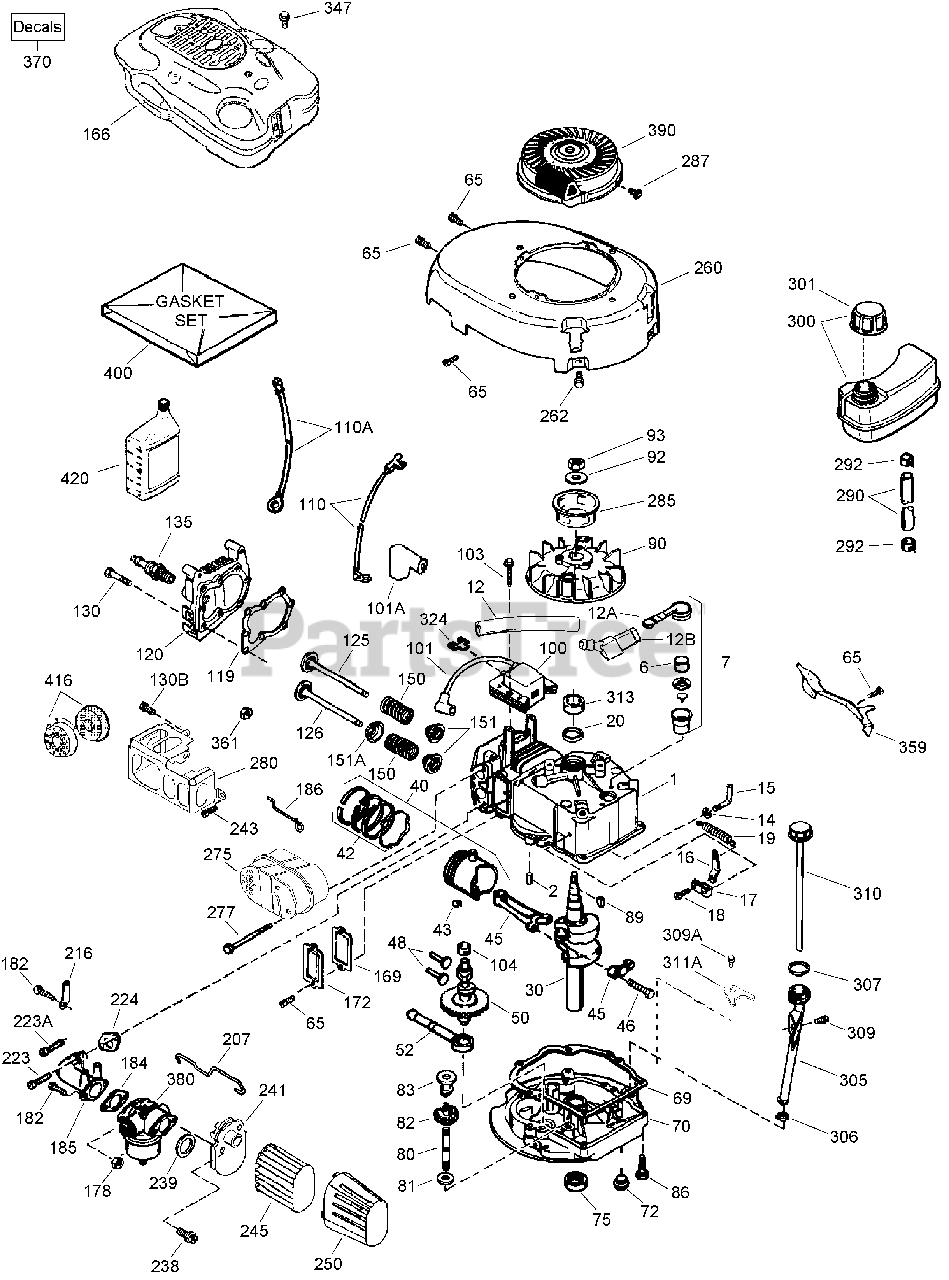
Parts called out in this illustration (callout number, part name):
1	Cylinder ASM (Includes 2 and 20)
2	Pin-Dowel
6	Element-Breather
7	Breather ASM (Includes 6 and 12A)
12	Tube-Breather
12A	Breather Cover and Tube ASM (Includes 12B)
12B	Elbow-Tube, Breather
14	Washer-Flat
15	Governor Rod ASM (Includes 14)
16	Lever-Governor
17	Clamp-Lever, Governor
18	Screw (T-15, 8-32 x 19/64)
19	Spring-Extension
20	Seal-Oil
30	Crankshaft
40	Piston, Pin and Ring Set (STD) (Includes 42)
40	Piston, Pin and Ring Set (.010 OS) (Includes 42)
42	Ring Set (STD)
42	Ring Set (.010 O S)
43	Ring-Retaining, Piston Pin
45	Connecting Rod ASM (Includes 46)
46	Bolt-Rod, Connecting
48	Lifter-Valve
50	Camshaft ASM (Exhaust MCR) (Incudes 104)
52	Oil Pump ASM
65	Screw (10-24 x 9/16)
69	Gasket-Flange, Mounting
70	Mounting Flange ASM (Includes 72 thru 83, 306, 309A and 311A)
72	Plug-Drain, Oil (Flush Mount)
75	Seal-Oil
80	Shaft-Governor
81	Washer
82	Governor Gear ASM (Includes 81)
83	Spool-Governor
86	Screw (1/4-20 x 1-1/4)
89	Key-Flywheel
90	Flywheel
92	Washer-Belleville
93	Nut-Flywheel
100	Ignition-Solid State
101	Cover-Spark Plug
101A	Shield-Spark Plug L-Head
103	Screw (T-15, 10-24 x 15/16)
104	Bushing-Cam
110	Wire-Ground
110A	Wire-Ground (10.50 with male and female flag terminals)
119	Gasket-Head, Cylinder
120	Head-Cylinder
125	Valve-Exhaust (STD) (Includes 151)
125	Valve-Exhaust (1/32 OS) (Includes 151)
126	Valve-Intake (STD) (Includes 151)
130	Screw (5/16-18x1-1/2)
130B	Screw (1/4-20 x 1/2)
135	Spark Plug-Resistor (R J19 L M) (also available in Packaged Part 740081)
